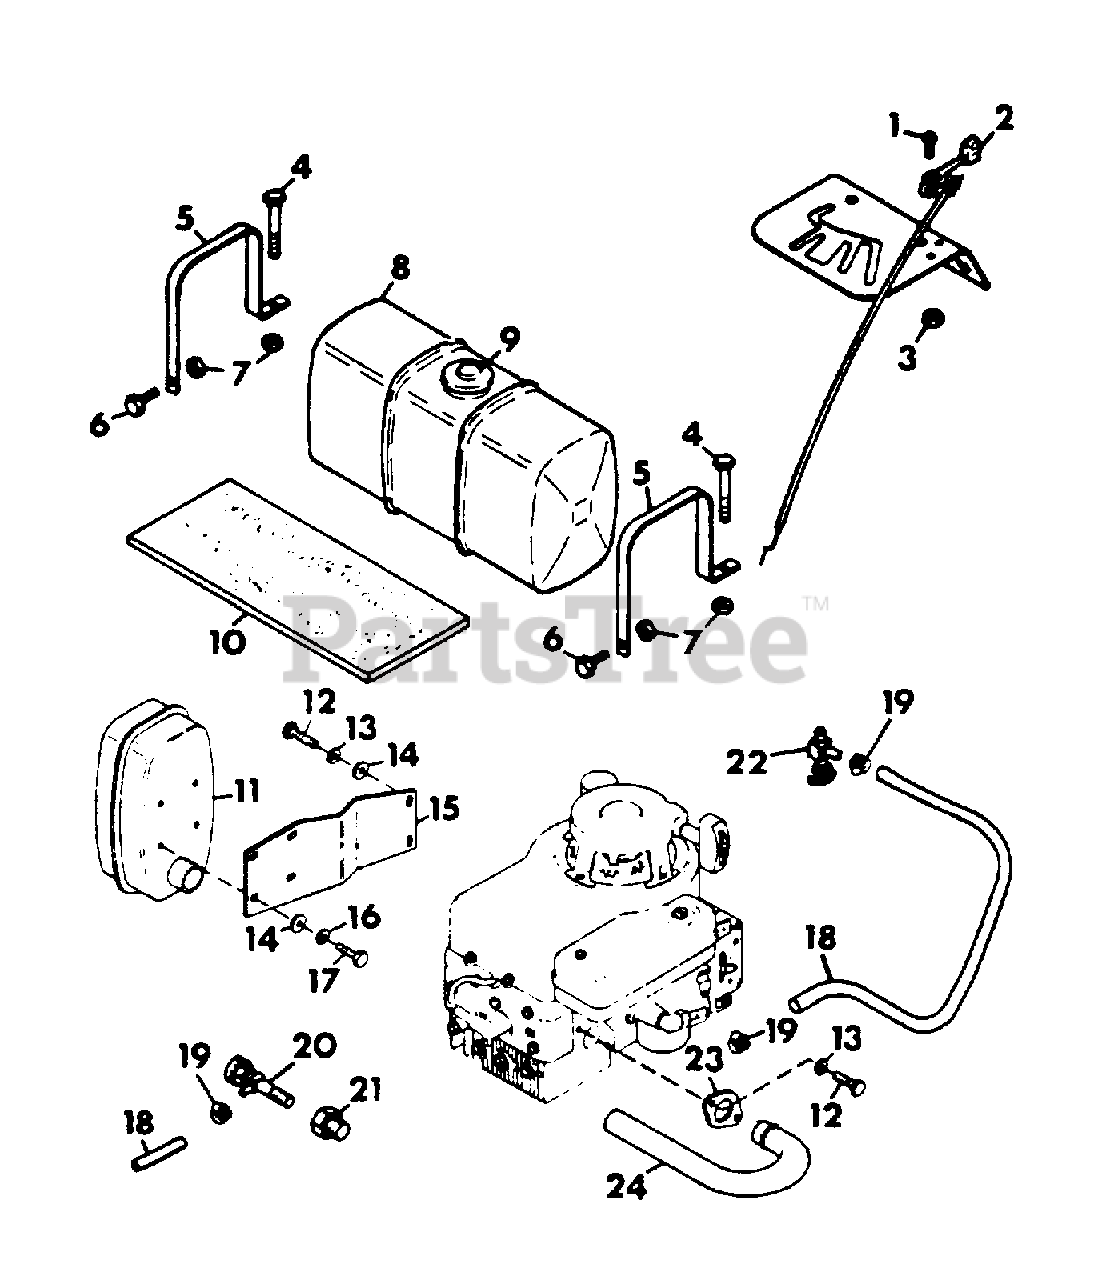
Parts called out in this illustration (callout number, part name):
1	SCREW, MACH. 10-24X.50 PHD
2	LEVER, THROTTLE CONTROL
3	NUT, LOCK 10-24
4	BOLT, HEX 1/4-20X1.75
5	STRAP, FUEL TANK
6	BOLT, HEX 1/4-20X.625
7	NUT, LOCK 1/4-20
8	TANK, FUEL (12 QTS.)
9	CAP, FUEL TANK
10	PAD, FUEL TANK
11	MUFFLER, 11 H.P. B & S
12	BOLT, HEX 5/16-18X.75
13	WASHER, LOCK 5/16 REG.
14	WASHER, FLAT .344X.688X.065
15	PLATE, EXHAUST
16	WASHER, LOCK 1/4 REG.
17	BOLT, HEX 1/4-20X.75
18	HOSE, FUEL
19	CLAMP, HOSE
20	COCK, OIL DRAIN
21	ADAPTOR, OIL DRAIN
22	VALVE AND STRAINER
23	FLANGE, MUFFLER
24	TUBE, EXHAUST
